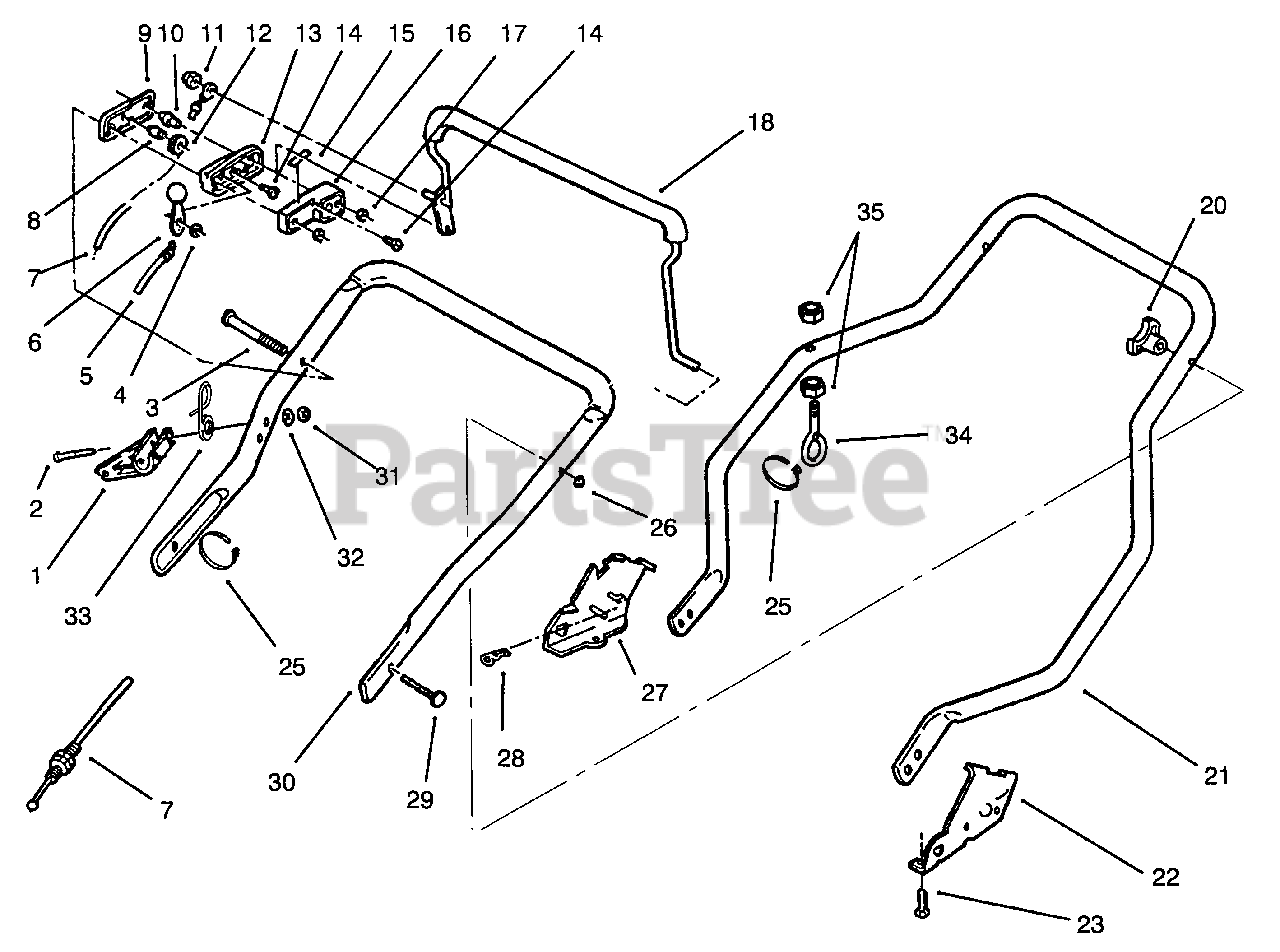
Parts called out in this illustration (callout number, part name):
1	Rope Guide Assembly
2	Screw-Truss Head
5	Cable-Throttle
6	Lever & Knob Assembly
7	Control Cable Assembly
9	Control Case Outer
11	Nut-Acorn
13	Case-Throttle, Center
15	Decal-Throttle
16	Case-Throttle, Inner
18	Lever-Control
20	Knob
21	Handle-Lower
22	Bracket-Handle L.H.
25	Tie Strap
26	Nut-Push
27	Bracket-Handle R.H.
28	Pin-Cotter
30	Handle Assembly-Top
31	Nut-Lock
33	Rope Stop
34	Eyebolt
35	Nut-Lock
